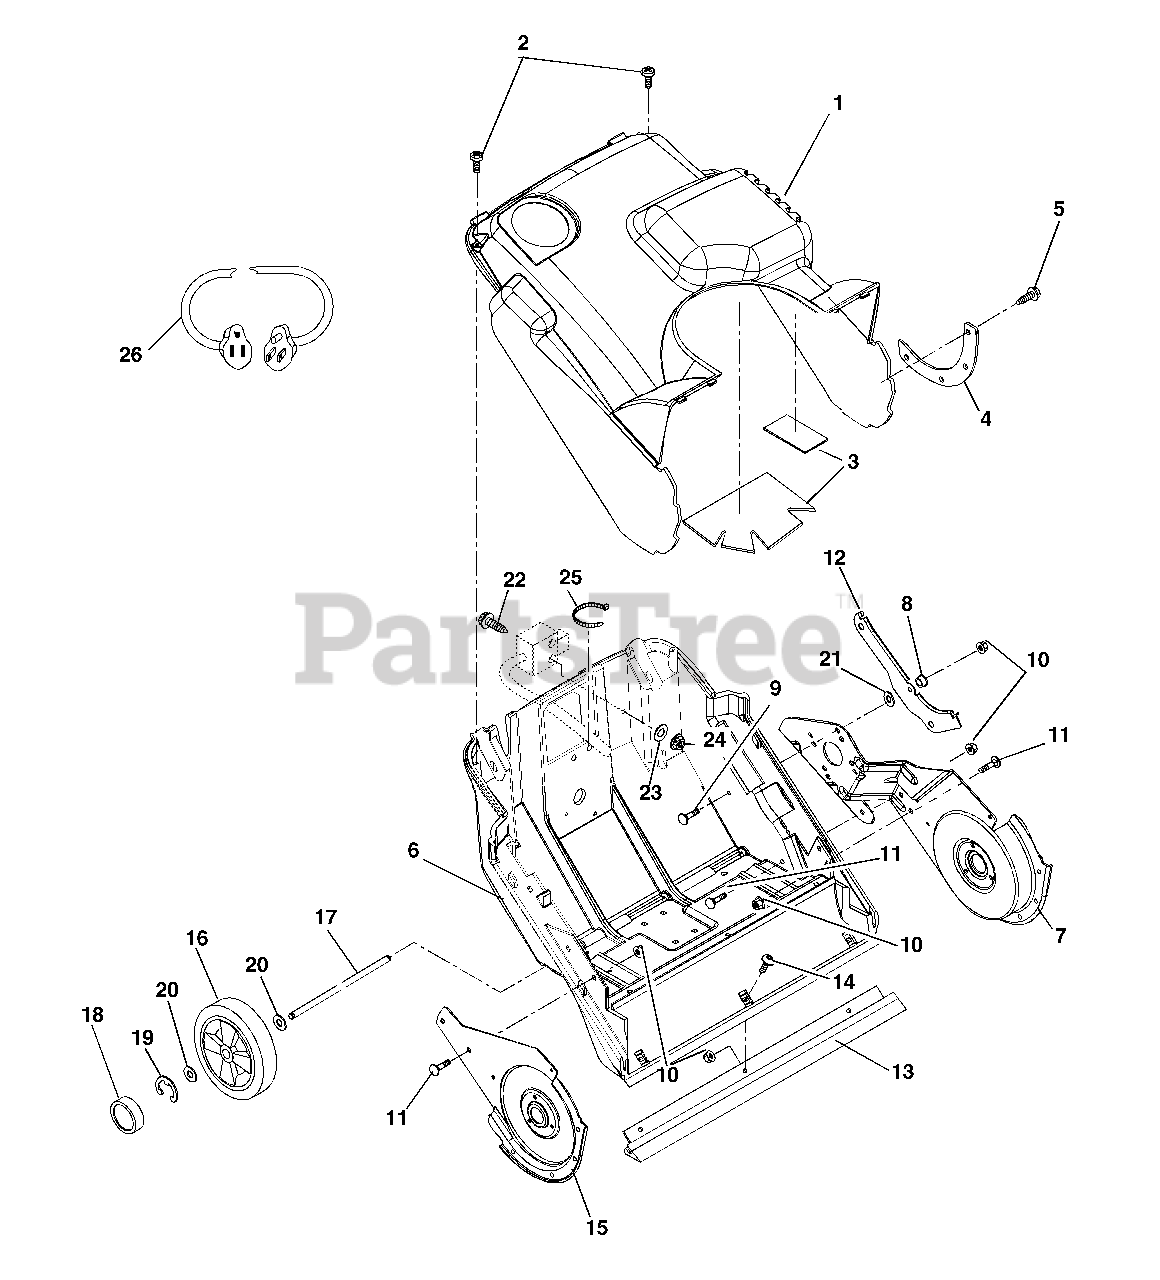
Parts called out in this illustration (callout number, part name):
1	COWL, REPLACEMENT - MACK
2	SCR-SPEC-TAP #10X1.0
3	SHEET-HEAT REFLECTIVE
4	PLATE-COWL RETAINER
5	SCR-TAP 12-24X.50 HWH TR BLACK
6	CHASSIS
7	SUPPORT-BRG,LH
8	BSHG-FLG .265X.437X.250X.750
9	@BLT-RDHDSQNK .25-20X1.25 G5YZ
10	NUT-LK-FLG .250-20 PL BLK
11	@BLT-RDHDSQNK .25-20X.75 G5YZ
12	GUIDE-CABLE
13	BLADE-SCRAPER
14	SCR-MCH .25-20X.75 TXTR YWZC
15	SUPPORT-BRG,RH
16	T/WHL ASSY 7.0X1.5
18	CAP-HUB
19	RG-RTNG-EXT .375X.035 TYP E
20	@WSHR-FL-STL.406X.812X.065 YWZ
21	@WSHR-FL-STL.312X.734X.065 YWZ
22	@SCR-MCH 8-32X2.75 HWH YWZC
23	@WSHR-FL-STL.219X.50X.049 YWZC
24	@NUT-LK-NYL 8-32 W/INSTR YWZC
25	CABLE TIE LG 5-1/2
26	CORD, ELECTRIC START CORD 120V
